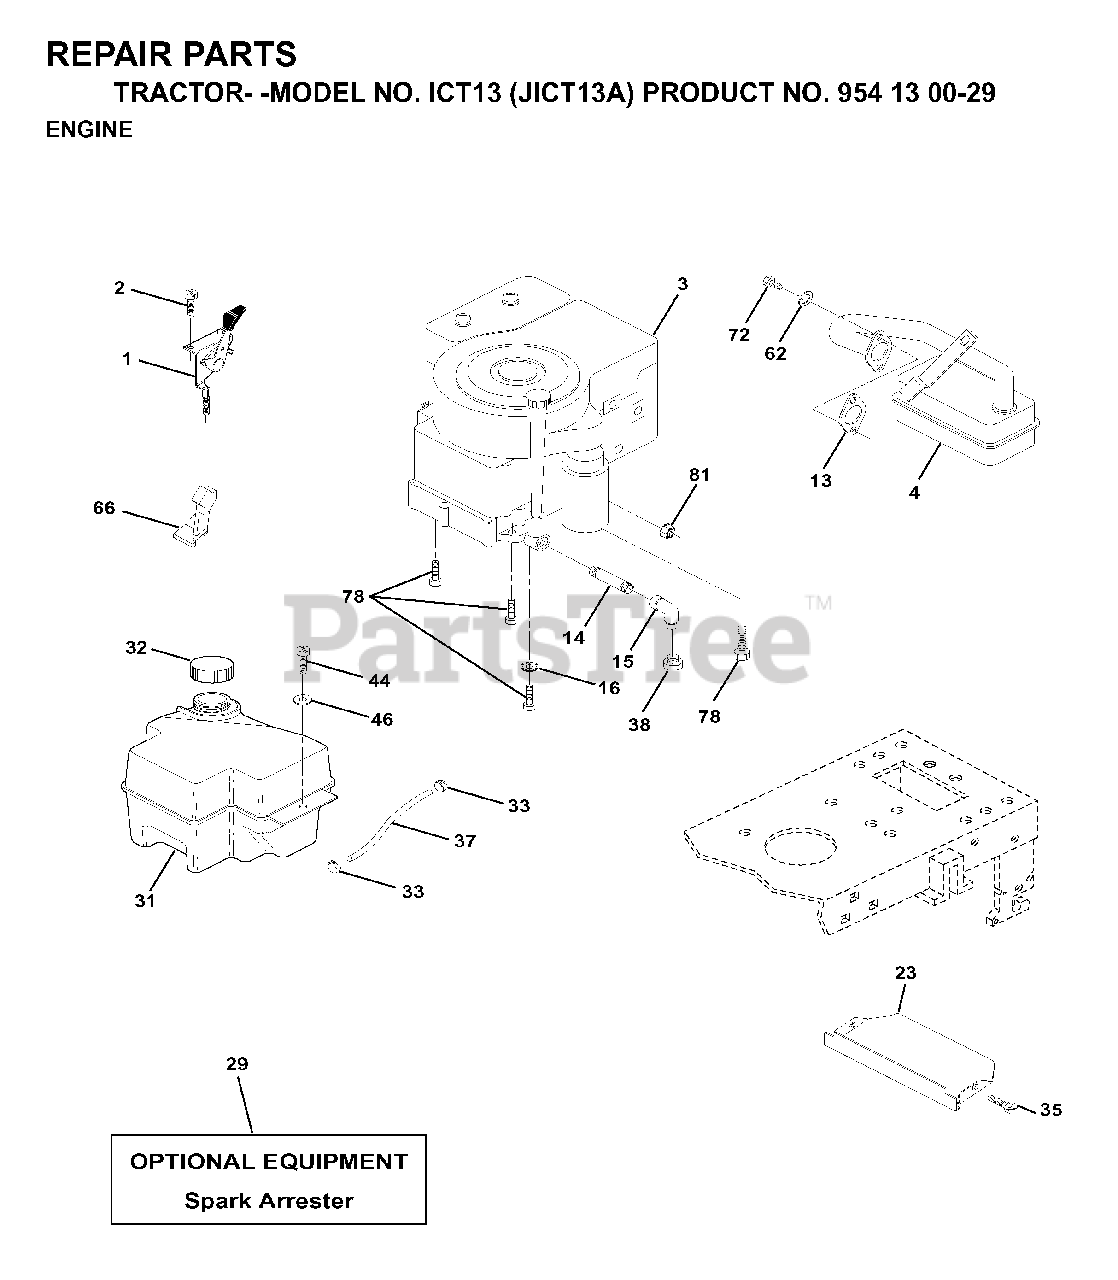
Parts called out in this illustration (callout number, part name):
1	CONTROL
2	SCREW LT
13	REPL BY 532 27 22-93
15	ELBOW
16	LOCKWASHER
23	PROTECTOR
29	ARRESTER SPARK (OPTIONAL)
31	FUEL TANK
32	FUEL CAP
33	HOSE CLAMP
35	SCREW
37	LINE.FUEL.20
44	SCREW HEX CRT
62	LOCKWASHER
66	STOP THROTTLE
72	SCREW
78	SCREW
81	NUT FLANGE 1/4-20 STARTER NUT
